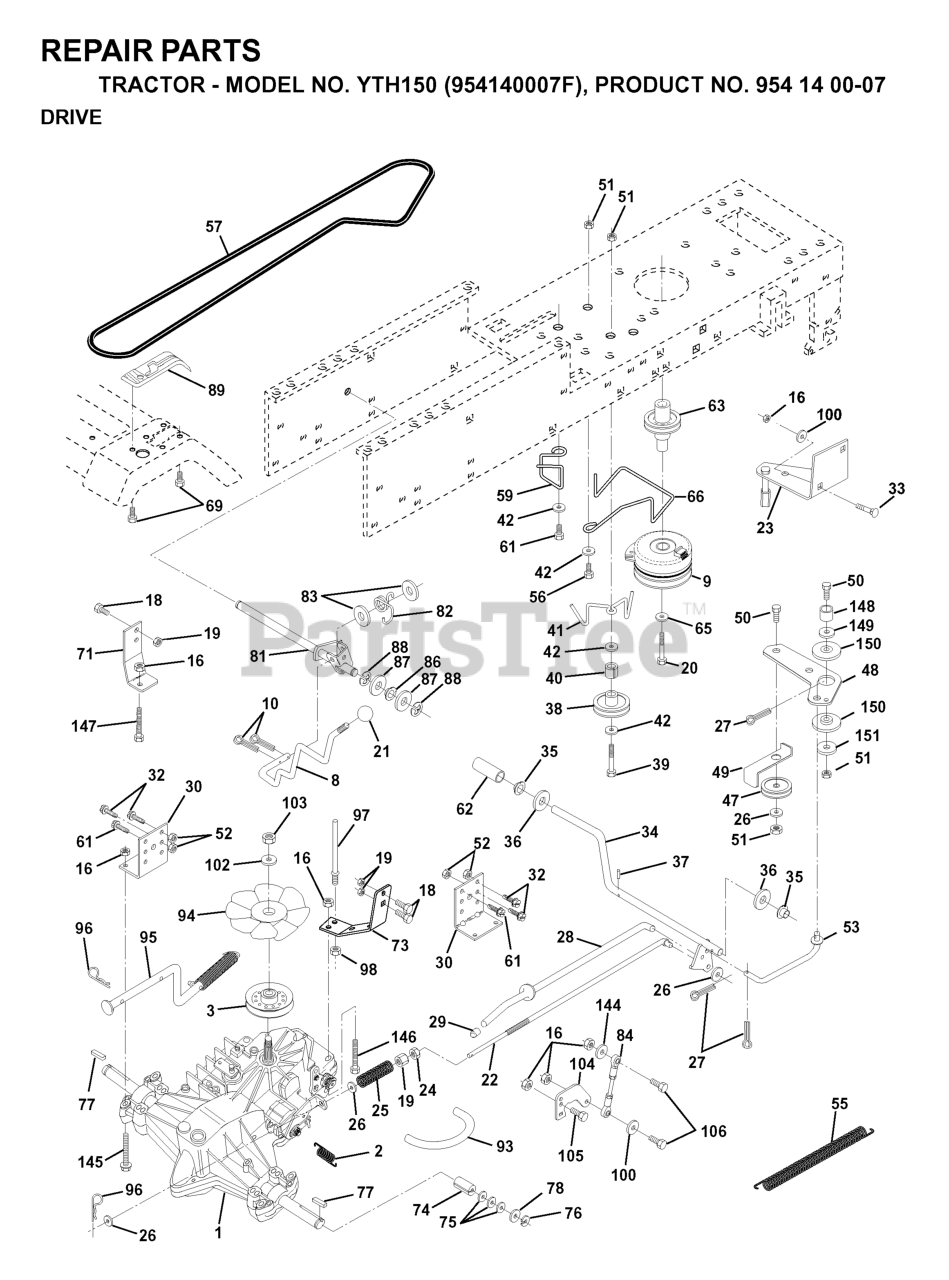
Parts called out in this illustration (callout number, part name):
1	TRANSAXLE ASSEMBLY
2	SPRING BRAKE
3	PULLEY, TRANSAXLE
8	ROD SHIFT FENDER
9	CLUTCH.ELECT.EVX.
10	PIN COTTER
16	NUT.71038.31-18.HEX.NYLOCK
19	NUT
20	BOLT HEX
21	KNOB.DELUXE.(PISTOL.GRIP).BLAC
22	ROD BRAKE HYDRO
23	BRACKET, ASM CLUTCH MTG
24	NUT
25	SPRING ROD LT
26	WASHER
27	COTTER PIN
28	ROD BRAKE PARK LT
29	PLUNGER CAP
30	BRACKET TRANSAXLE
32	BOLT
33	RP BOLT 5/16-18 X3/4 ZN/YEL GR
34	SHAFT, FOOT PEDAL
35	BEARING.NYLON
37	DRIVE PIN
38	PULLEY.IDLER.FLAT
41	KEEPER, BELT IDLER
42	WASHER
47	IDLER PULLEY
48	BELLCRANK, CLUTCH
49	RETAIN BELT
50	BOLT
52	LOCKNUT
53	LINK, CLUTCH LT
55	SPRING, RETURN LT
57	DRIVE BELT, LTH & YTH TRACTORS
59	KEEPER CENTER SPAN
61	SCREW
62	COVER, PEDAL (1 2)
63	PULLEY, CLUTCH ELECT EVX
65	LOCKWASHER
66	KEEPER BELT ENGINE
71	STRAP LH TORQUE
73	STRAP TORQUE RH HYDRO
74	SPACER SPLIT
77	SQUARE KEY
81	SHAFT ASSY
82	SPRING,TORSION
83	WASHER
86	BUSHING.STEERING.ROD LTB-WSL
89	SHIFT CONSOLE
90	NUT.PUSH.3/16
93	LINE FUEL HYD 4"
94	FAN 7" HYDRO
95	CONTROL ARM, BYPASS HYDRO
96	RETAINER M
97	KEEPER BELT RH
100	WASHER M
103	NUT.HEX.1/2-20
104	CONTROL ARM
106	BOLT.5/16-18X1-1/4 FULL.THREAD
144	Washer 11/32 x 5/8 x 16 Ga SD
146	Bolt Hex Flanged 5/16-18 Unc x 2
147	Bolt Hex Flanged 5/16-18 Unc x 2
149	SPACER RETAINER
150	BUSHING NYLON COLLERED
151	WASHER 12/32X2X10GA
